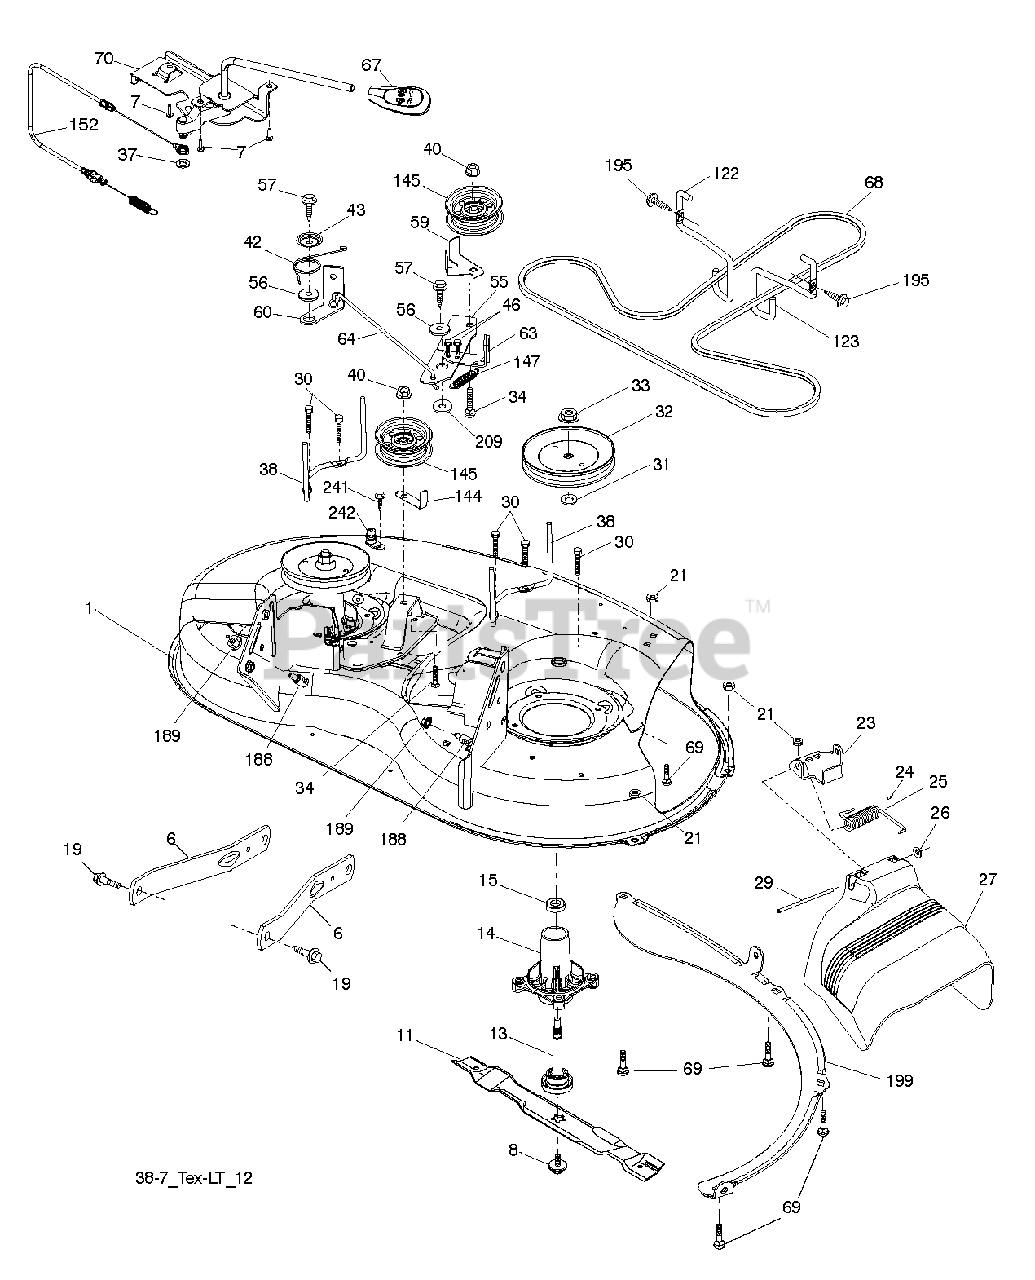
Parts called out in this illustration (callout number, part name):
6	ARM.SUSPENSION.MOWER.R
7	SCREW.#10 X 0.750.BOS THREAD
8	BOLT.WASHER.ASM.7/16-2
11	BLADE 38" PREMIUM
13	SHAFT.ASM.MDRL.N/GREASE.38
14	HOUSING MANDREL
19	BOLT.SHOULDER
21	LOCKNUT
23	BRKT.DEFLECTOR.38"2005+
24	CAP-SLEEVE LT
25	SPRING.TORSION.DEFLECT
26	NUT PUSH M
29	ROD.HINGE
30	SCREW, WASHER HEAD
31	WASHER.SPACER.MANDREL
32	PULLEY.MANDREL.5.0.PD.38"
33	NUT.FLANGE.LOCK.TOP
34	BOLT.3/8-16X1.50
38	KEEPER BELT LH MANDREL
40	NUT LOCK FLG 3/8-16 UNC
42	SPRING.TORSION.BRAKE
43	SRPING.TORSION.RETAINE
46	SCREW.1/4-20X5/8
55	IDLER.ARM
56	SPACER.RETAINER
57	SCREW 3/8-16X1
59	GUARD, BELT
60	ARM BRAKE MOWER RH 38"
63	ARM BRAKE MOWER RH
64	LINK BRAKE
67	HANDLE.CLUTCH.CABLE.LT
69	BOLT
70	CLUTCH.ASM.MANUAL.LT.PRED
122	KEEPER BELT ENGINE LH
123	KEEPER BELT RH
144	KEEPER BELT
145	PULLEY.IDLER.48"PRIMARY
147	SPRING RETURN
152	CABLE.CLUTCH.MANUAL.
188	STUD.FASTNER.W/ANTI-ROTATE
189	NUT LOCK HEX FLANGE 5/16-18
195	SCREW, 3/8-16X3/4
199	BAFFLE VORTEX
209	WASHER 12/32X2X10GA
242	PORT.WASHOUT
